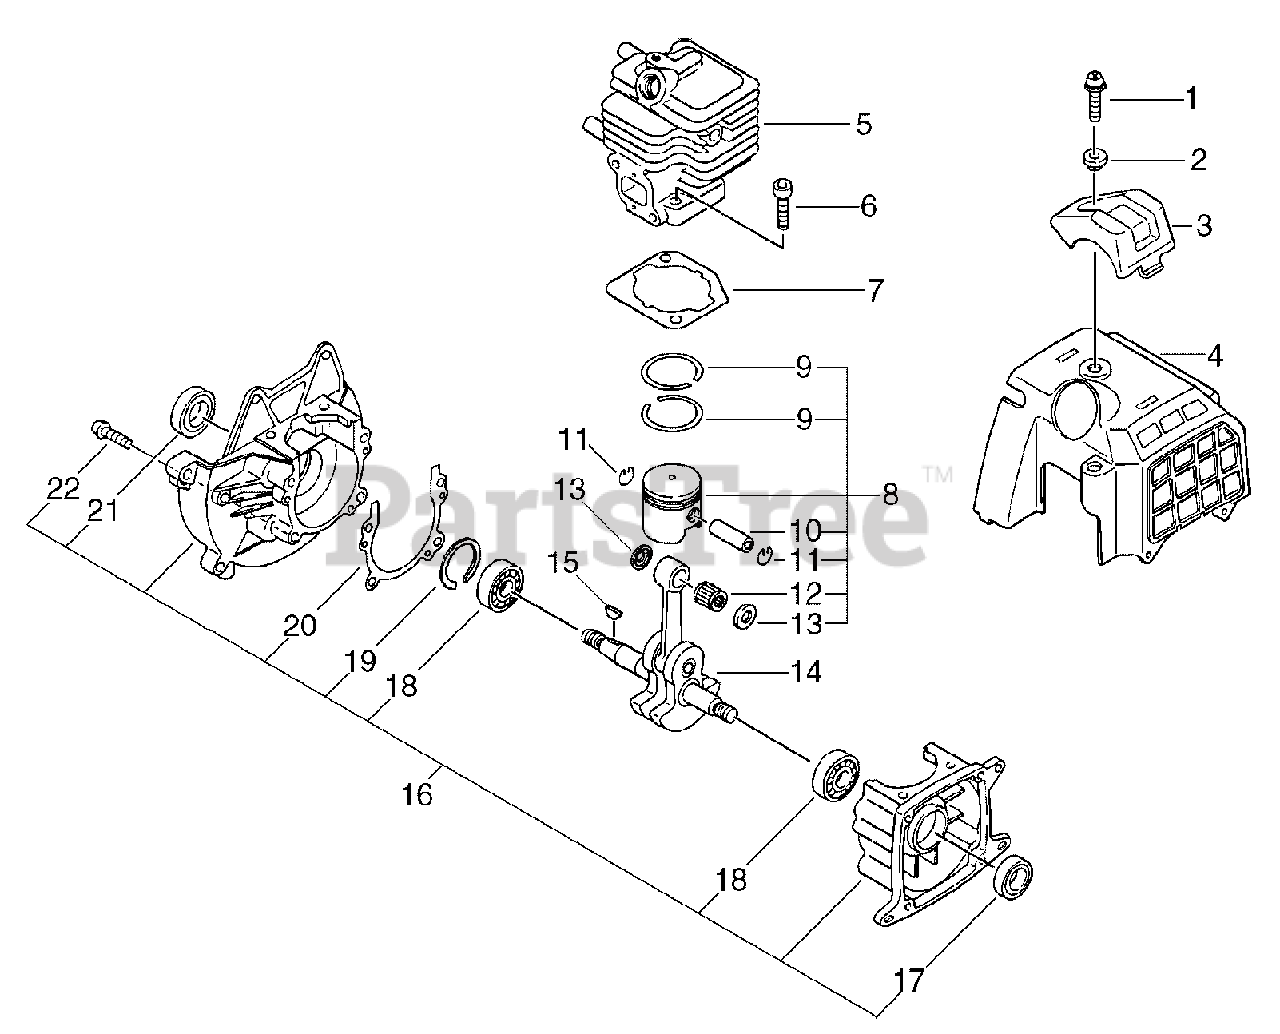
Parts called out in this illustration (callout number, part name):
1	BOLT - 5X20 -- FLANGE
2	COLLAR - 5
3	GUARD - TOP
4	COVER, ENGINE
5	CYLINDER
6	SCREW - 5X22
7	GASKET, CYLINDER
8	PISTON KIT
9	RING, PISTON
10	PIN, PISTON
11	RING, RETAINING
12	BEARING, NEEDLE - 8
13	SPACER, PISTON
14	CRANKSHAFT ASSY
16	CRANKCASE KIT
17	SEAL, OIL
18	BEARING, BALL - 6001
19	RING, RETAINING - 28
20	GASKET, CRANKCASE
21	SEAL, OIL - 12
22	SCREW - 5X25
